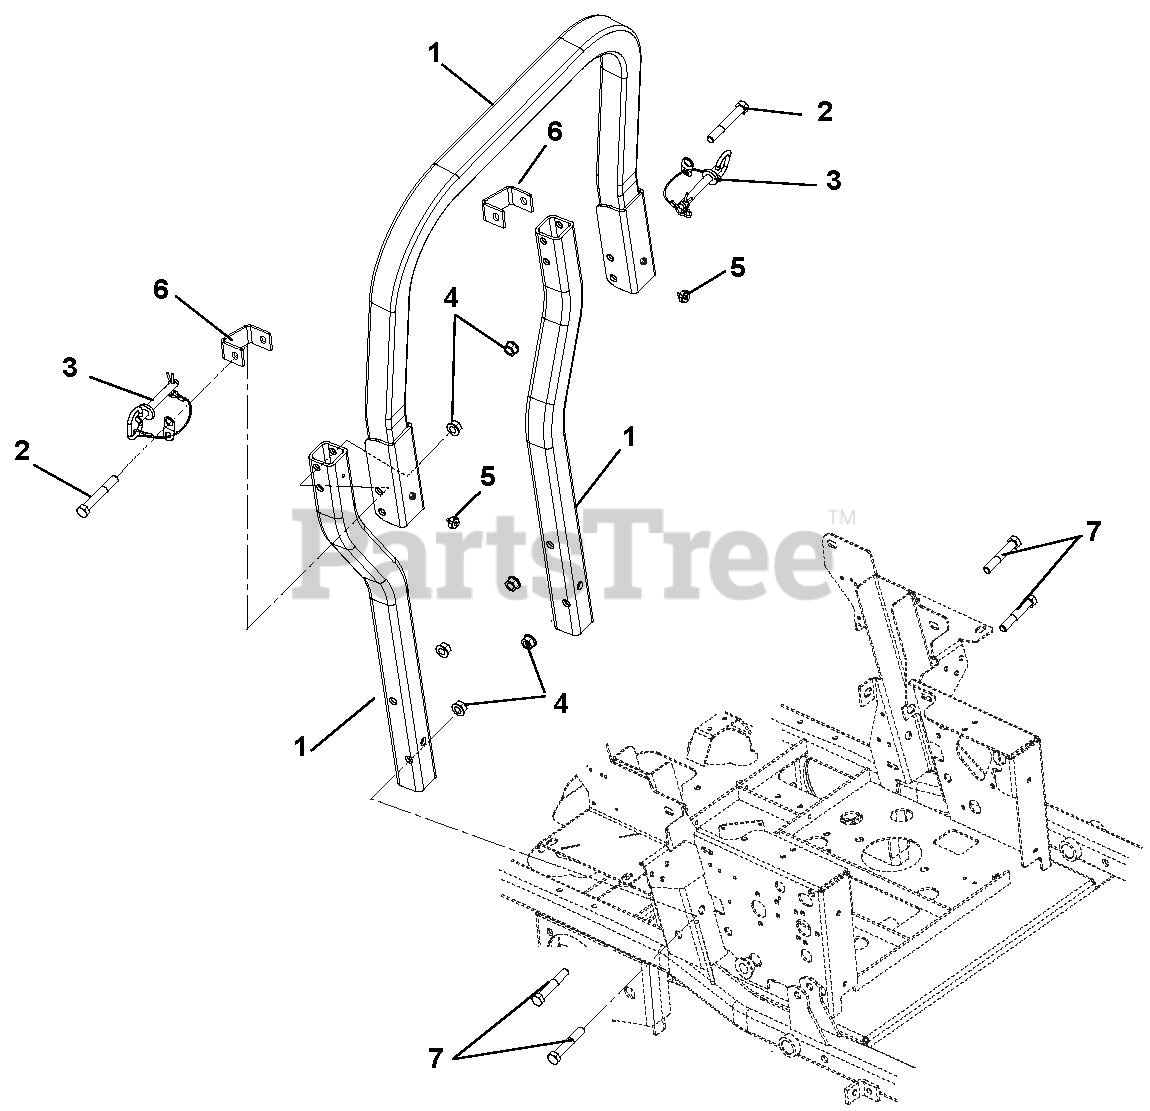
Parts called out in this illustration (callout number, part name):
1	ROPS, PM200 Replacement Kit
2	Bolt, Hex .50-13 x 3.50 Grade 5
3	Assembly, ROPS Pin/Lanyard
4	Nut, Locking Top Flange .50-13
5	Knob, Round .312-18 x .750
5	Clip, ROPS Anti-Rattle
6	Bracket, ROPS Stop
7	Bolt, Hex .50-13 x 3.00 Grade 5
